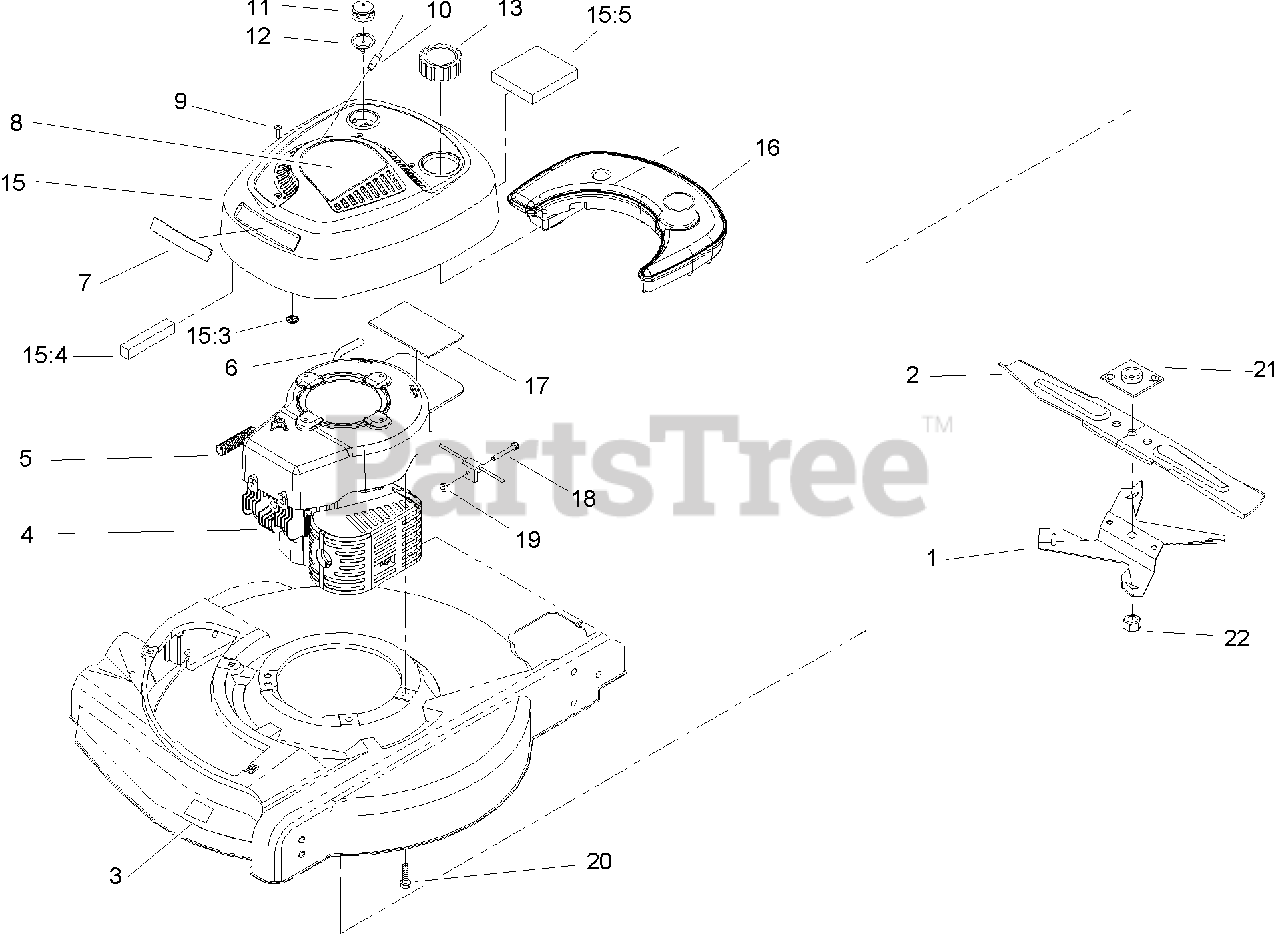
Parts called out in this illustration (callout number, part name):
1	FAN-MULCHING
3	DECAL-DECK
4	Engine ASM
5	SPRING-COMPRESSION
6	LINE-FUEL
7	APPLIQUE-SHROUD
8	DECAL-RECOIL
10	STOP-ROPE
11	BODY-PRIMER
12	BULB-PRIMER
13	FUEL AND OIL CAP ASM
15	SHROUD and RECOIL COVER ASM
15:3	NUT-PUSH
15:4	STRIP-FOAM
15:5	STRIP-FOAM
17	PAD-FOAM
19	NUT-HEX
20	SCREW-HH
21	PLATE AND COLLAR ASM
22	NUT-BLADE
